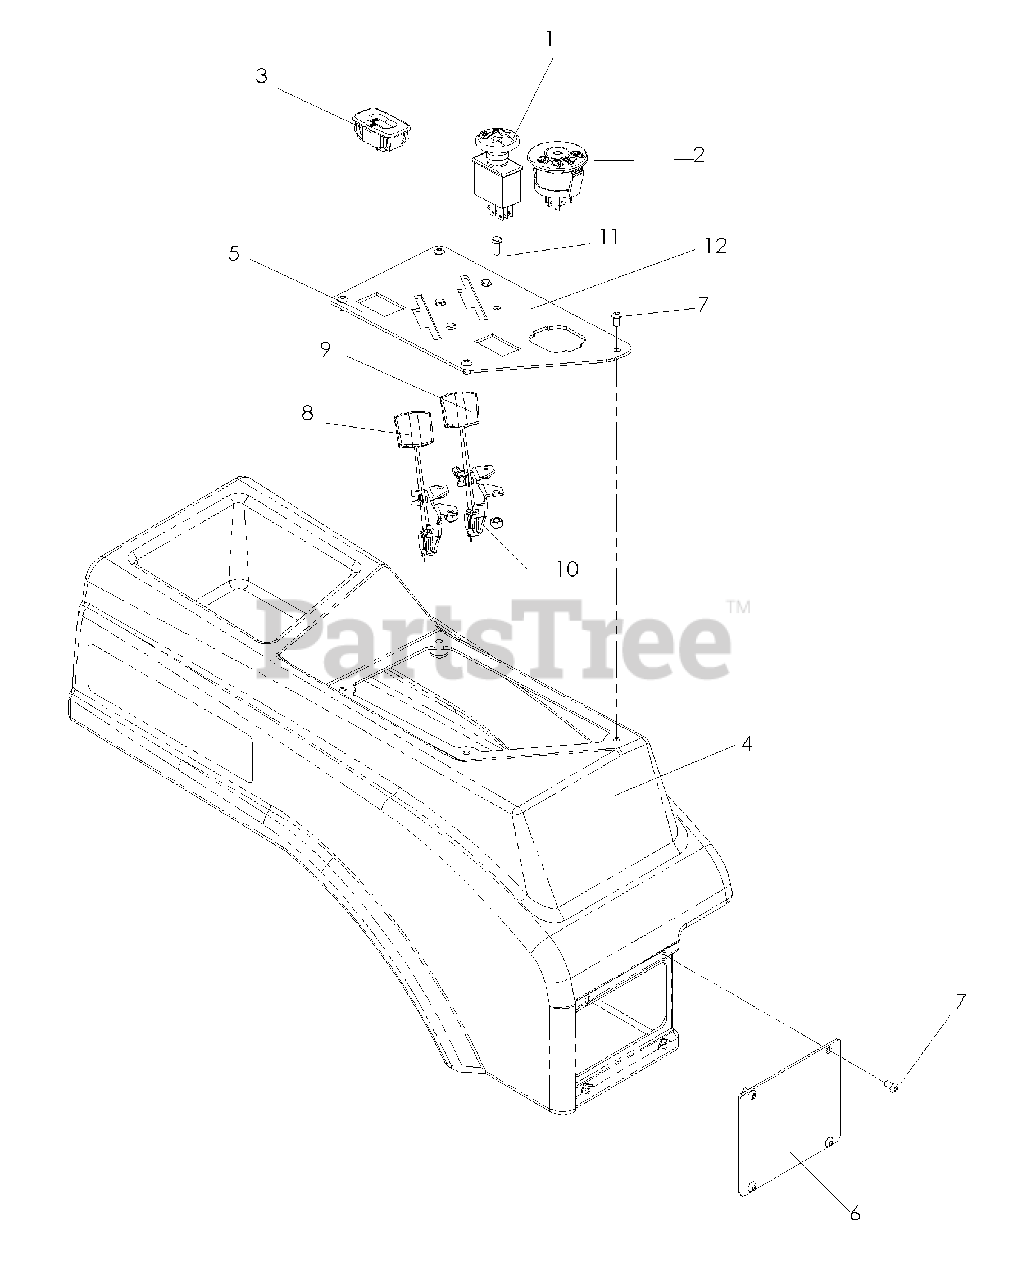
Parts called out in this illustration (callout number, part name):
1	SWITCH, BLADE
2	IGNITION SWITCH
3	HOUR METER
4	TANK, CONSOLE, RT
5	CONTROL PANEL
6	PANEL, LIGHT DELETE
7	SCR #10-24 X 3/8 SKT HD BLK OX
8	CABLE THROTTLE
9	CABLE CHOKE
10	NUT 10-24 NYLOC
11	HCS #10-24 X 1/2
12	DECAL, CONTROL
